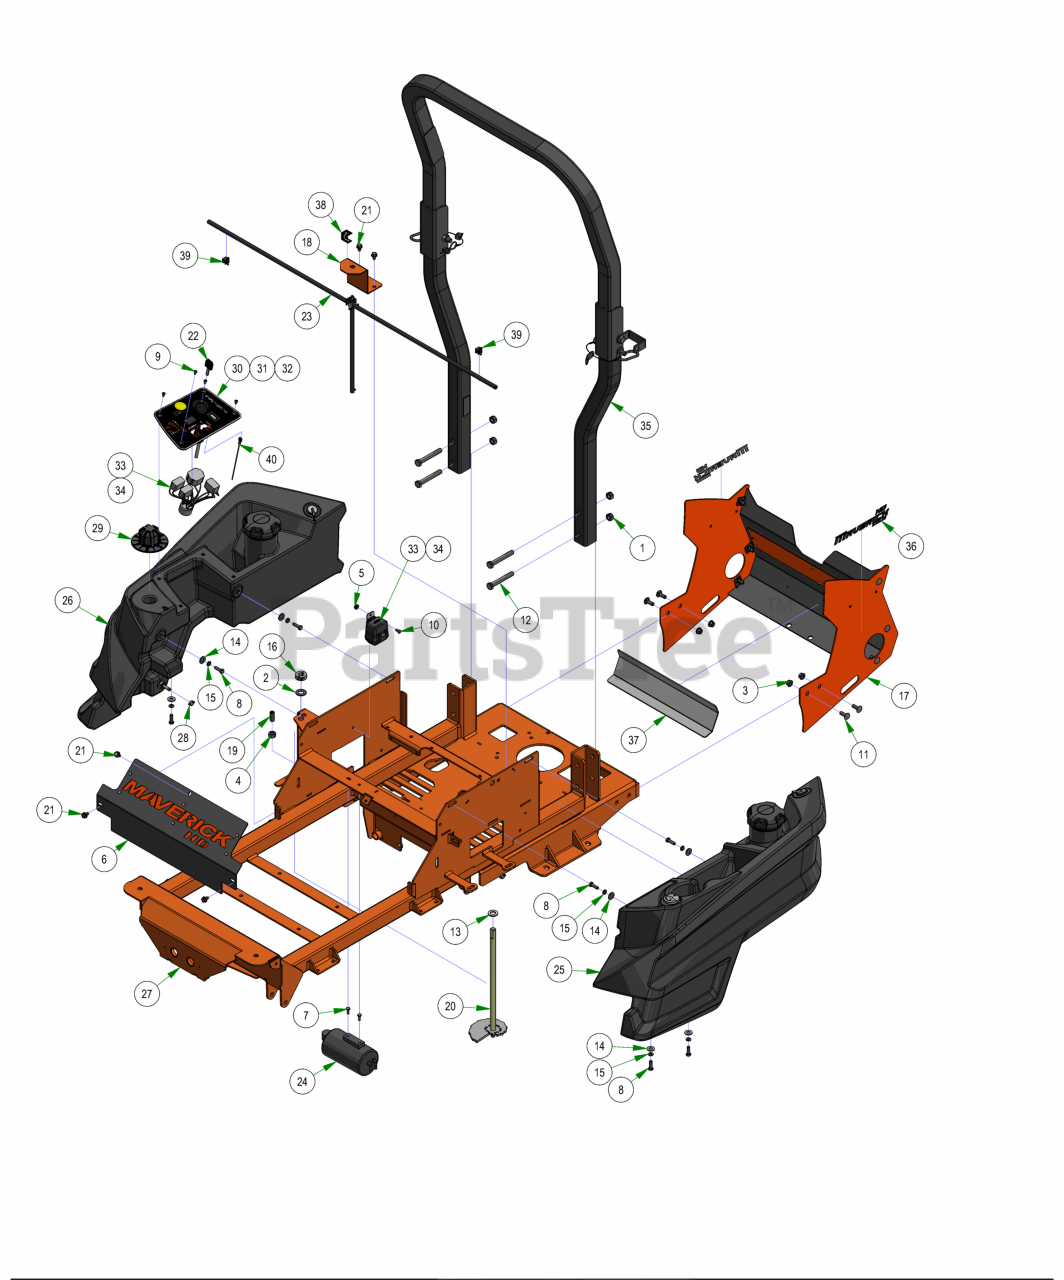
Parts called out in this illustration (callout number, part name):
1	1/2-13 HEX 2-WAY REVERSIBLE CENTER LOCKNUT Grade B ZINC
2	.625 ID x 1.250 OD x .062 THK F/W Nylon
3	3/8-16 NYLON INSERT FLANGE LOCKNUT (GR.F) ZINC
4	1/2-13 HEX NUT ZINC
5	1/4-20 HEX SERRATED FLANGE NUT HARD/ZINC
6	Maverick HD Cooler Cover
7	M6-1.0 X 16MM DIN 933 HEX TAP BOLT (CL 8.8) ZINC
8	5/16-18 X 1 HEX CAP SCREW (GR.5) ZINC
9	10-32 X 3/8 BUTTON SOCKET CAP SCREW 18-8 STAINLESS STEEL
10	1/4-20 X 1/2 BUTTON SOCKET CAP SCREW 18-8 STAINLESS STEEL
11	3/8-16 X 1 CARRIAGE BOLT (GR.5) ZINC
12	1/2-13 X 3-1/2 HEX CAP SCREW (GR.5) ZINC
13	.635 ID X 1.120 OD X .140 THICK FLAT WASHER NYLON
14	5/16 USS FLAT WASHER (7/8 OD) ZINC
15	5/16 SPLIT LOCKWASHER ZINC
16	5/8" Split Collar
17	2022 Maverick Rear Cover Assembly
18	Fuel Shut Off Mounting Plate
19	Dial Rod Plunger
20	ZT Deck Height Bar Assembly
21	5/16-18 X 1/2 HWH unslot (F) tcs zinc
22	Ignition Key
23	2023 Maverick HD Fuel Line with Shutoff
24	2023 HD Kohler/Kawasaki EPA Canister Assembly
25	2021 Maverick Left Side Tank
26	2022 Maverick HD RH Fuel Tank
27	2025 Maverick Frame
28	2 EAR CLAMP 12.5mm-15mm
29	MZ/ZT Deck Height Dial
30	Maverick HD EFI Control Panel Assy
31	2023 Control Panel Assembly
32	2025 ZT/MAV/HD Control Panel Assembly
33	2024 Wiring Harness with Clips
34	2025 Wiring Harness with Clips and Lights
35	2016 2x2 ROPS
36	Maverick HD Back Plate Decal
37	Heat Shield (Fiberglass Adhesive)
38	Maverick HD Shut Off Valve Decal
39	Edge Clip With Ziptie
40	2017 MZ/ZT/MAV Tach Wire Assy
